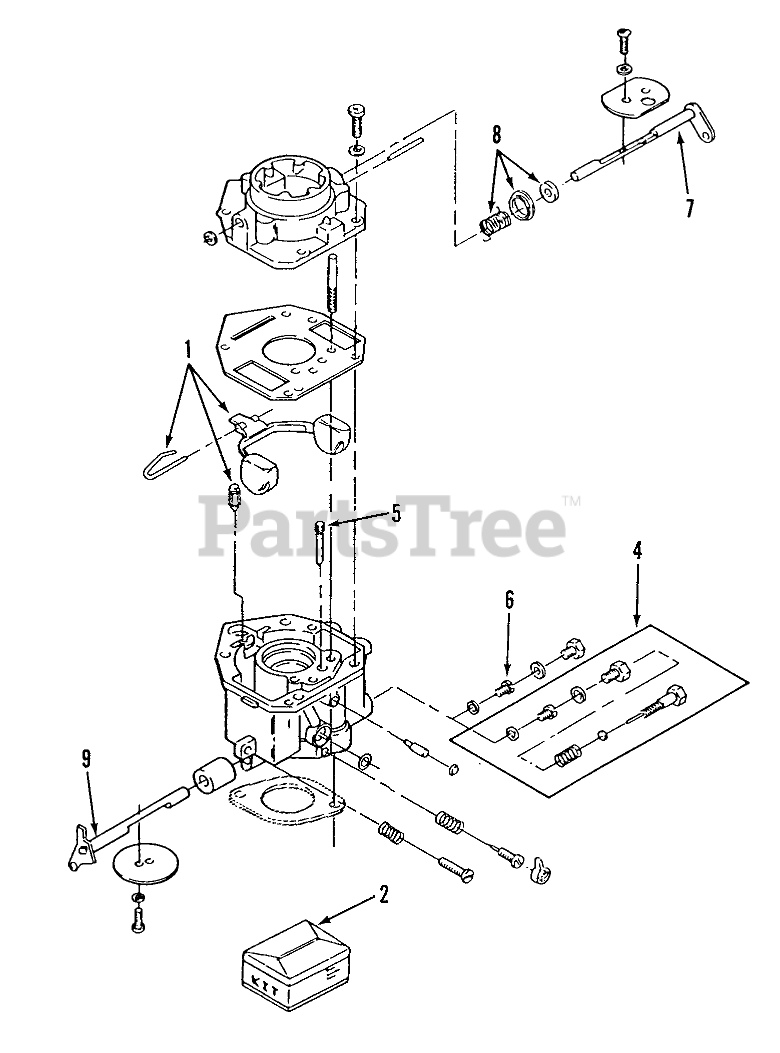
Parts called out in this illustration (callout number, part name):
1	Float Kit (Includes Float, Pin and Valve)
2	Repair Kit (Includes Screw and Plug Package, Gasket Package, Float Valve, Idle Adjustment Needle and Spring, Mounting Gaskets, Idle Limit Cap)
4	Variable Jet Kit-Optional (High Altitude Application Includes Power Jet and Gasket, Retainer, Power Needle Spring, Power Needle and Power Plug Gasket)
5	Idle Jet
6	Power Jet
7	Choke Shaft Kit (Includes Choke Valve, Valve Set Screw and Air Filter)
8	Choke Lever Kit (Includes Choke Lever Ring, Choke Spring and Choke Collar)
9	Throttle Shaft Kit (Includes Valve Set Screw, Air Filter and Throttle Valve)
